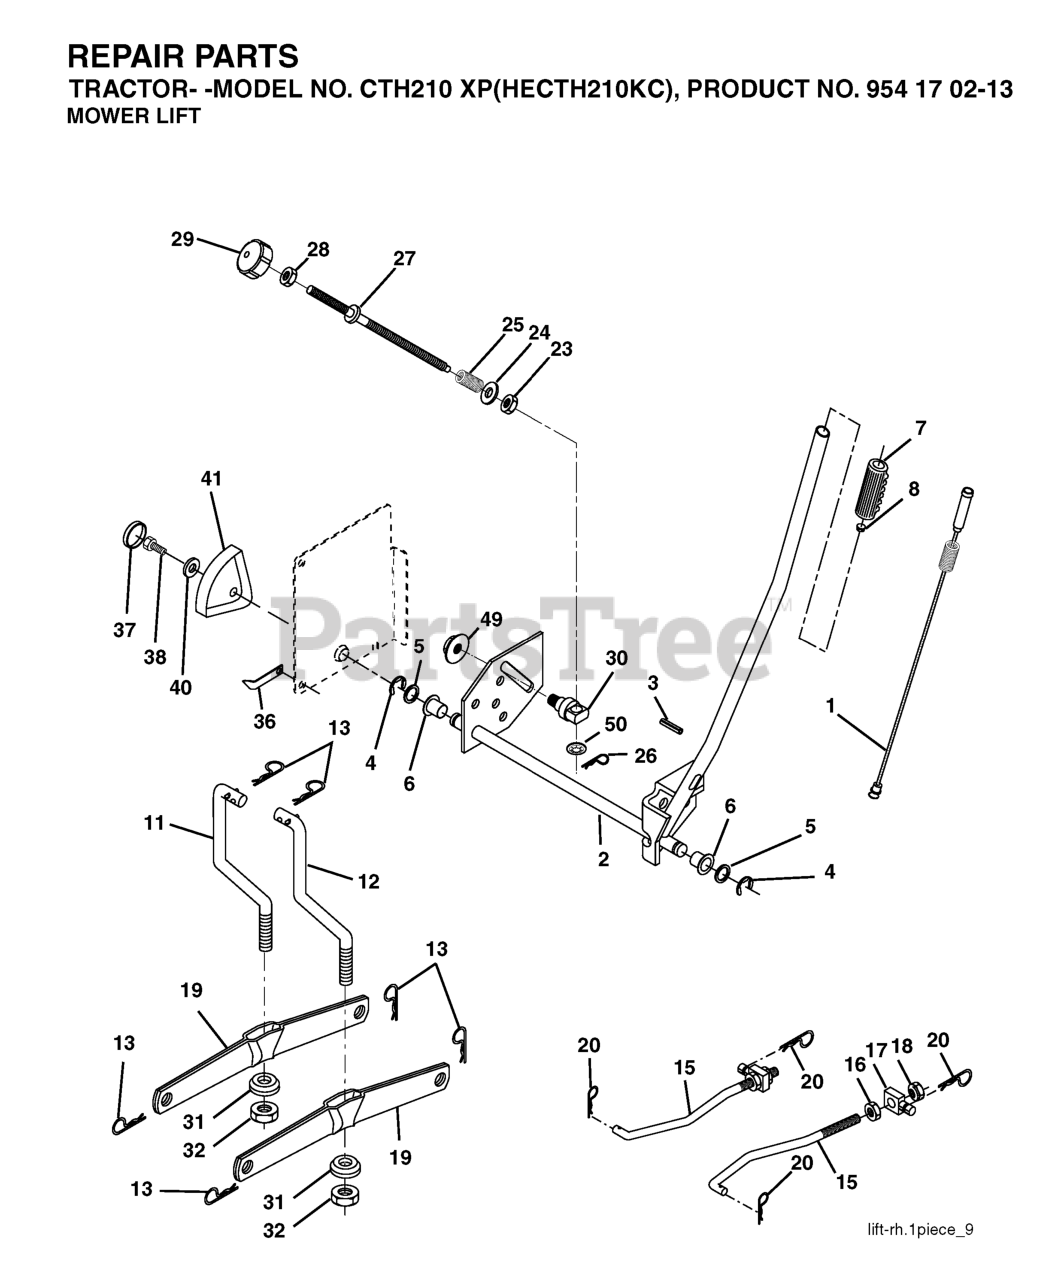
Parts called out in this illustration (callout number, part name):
1	WIRE ASM INNER W/ PLUNGER LT
2	SHAFT ASM R HANDLE
3	PIN GROOVE.
4	RETAINING RING LT
6	BEARING.NYLON
7	GRIP HANDLE
8	PLUNGER BUT KIT
11	LINK
12	LINK
13	RETAINER-SPRNG RB
15	LINK.SUSPENSION.FRONT
16	NUT.HEX.JAM.1/2-13
18	NUT.LK.W/WSH.1/2.
19	ARM.REAR.SUSPENSION
20	SPRING RETAINER
25	SPRING**
26	RETAINER CLIP
27	ROD ADJ LIFT
28	NUT
29	KNOB INF 3/8-16
31	BEARING.PIVOT.LIFT
32	NUT CROWNLOCK 3/8-24
36	POINTER, HEIGHT INDICATOR(2 2)
38	SCREW 5/16-18X1
41	HEIGHT INDICATOR
49	NUT
50	NUT PUSH M
